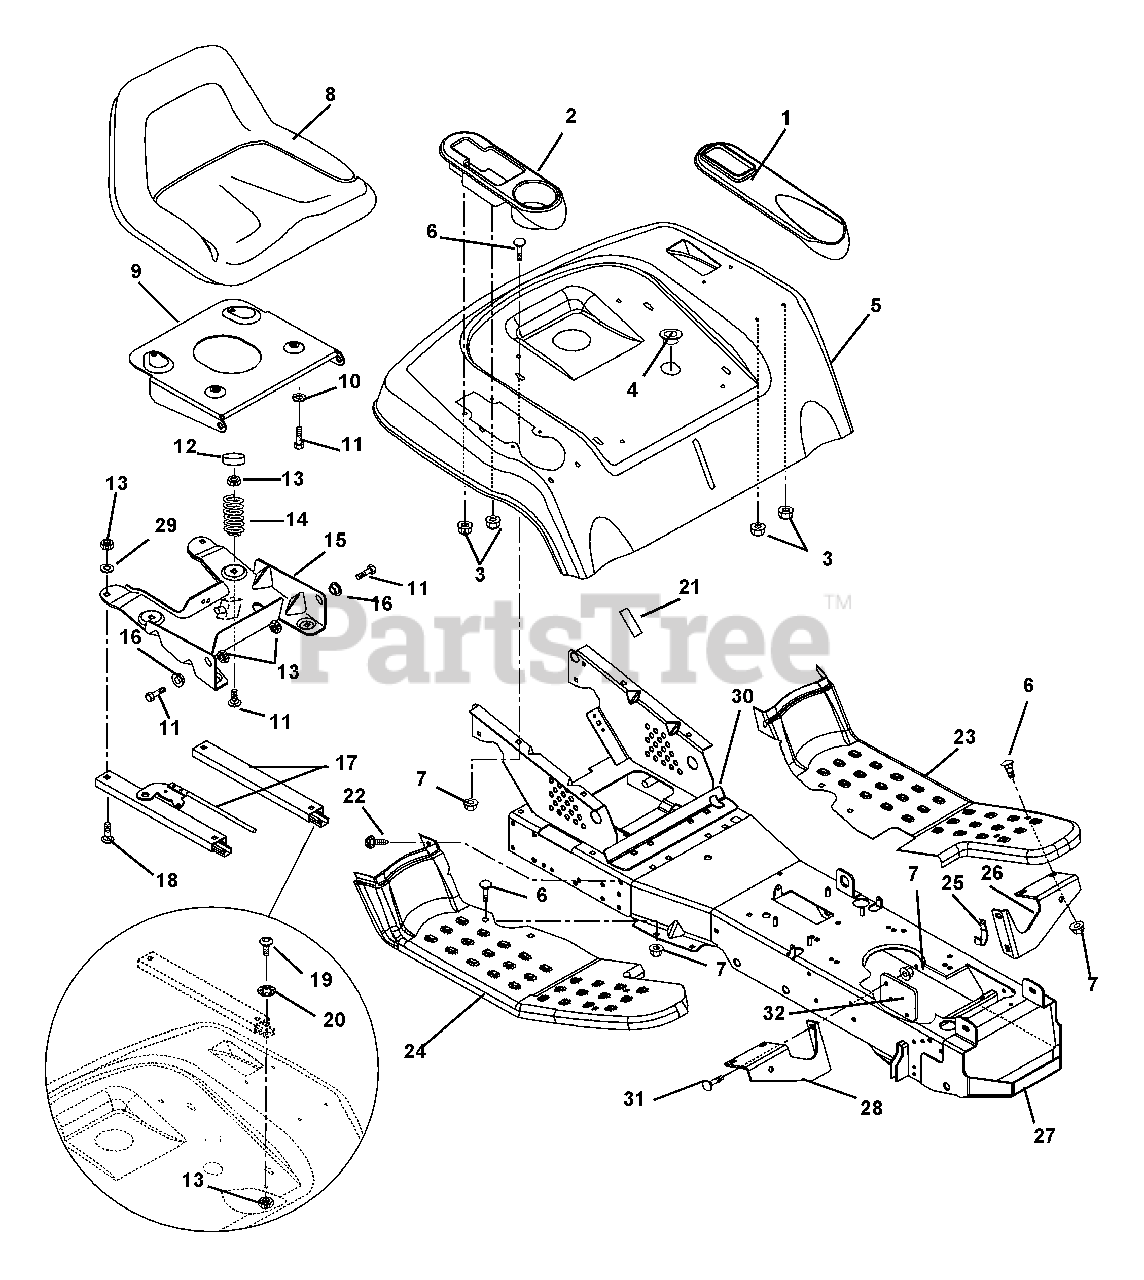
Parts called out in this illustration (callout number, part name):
1	INSERT- LIFT
2	INSERT - BEVERAGE
3	NUT-SELF-THRDNG FITS.25 STUDPL
4	SNAP BUSHING
5	REAR DECK
6	@BLT-RHDSSQNK .31-18X.62 G5YZ
7	@NUT-SPNLK-FLG .312-18 YWZC
8	SEAT
9	PLATE, SEAT PIVOT
10	WSHR-LK .312X.097 HVY YWZC
11	@BLT-HEX .31-18X.75 GR5 YWZC
12	TUBE CAP
13	@NUT-LK-CTR .31-18 YWZC
14	SG-COMP .148X1.23X2.41 WLD87
15	SEAT BOX
16	BSHG-FLG .325X.465X.333X.685
17	SEAT SLIDES -(RAME TAK-3010-4)
18	BLT-RDHDSQSHK.31-18X.75 GR2 YW
19	SCR-CAP BTHD.31-18X.50 GR5 YZ
20	WSHR-LOCK INT .31 YWZC
21	PAD, FOAM
22	@SCR-TAP .31-18X.50 HWH TR YWZ
23	FOOT REST L.H.
24	FOOT REST R.H.
25	J-CLAMP
26	BRACE, FOOT REST LH
27	FRAME, MAIN (WELDMENT)
28	BRACE, FOOT REST RH
29	@WSHR-LK .31X.078 REG YWZC
30	PLATE, REINFORCING
31	@BLT-RDHDSQNK .31-18X1.00 G5YZ
32	PLATE-CRUISE CONTROL
